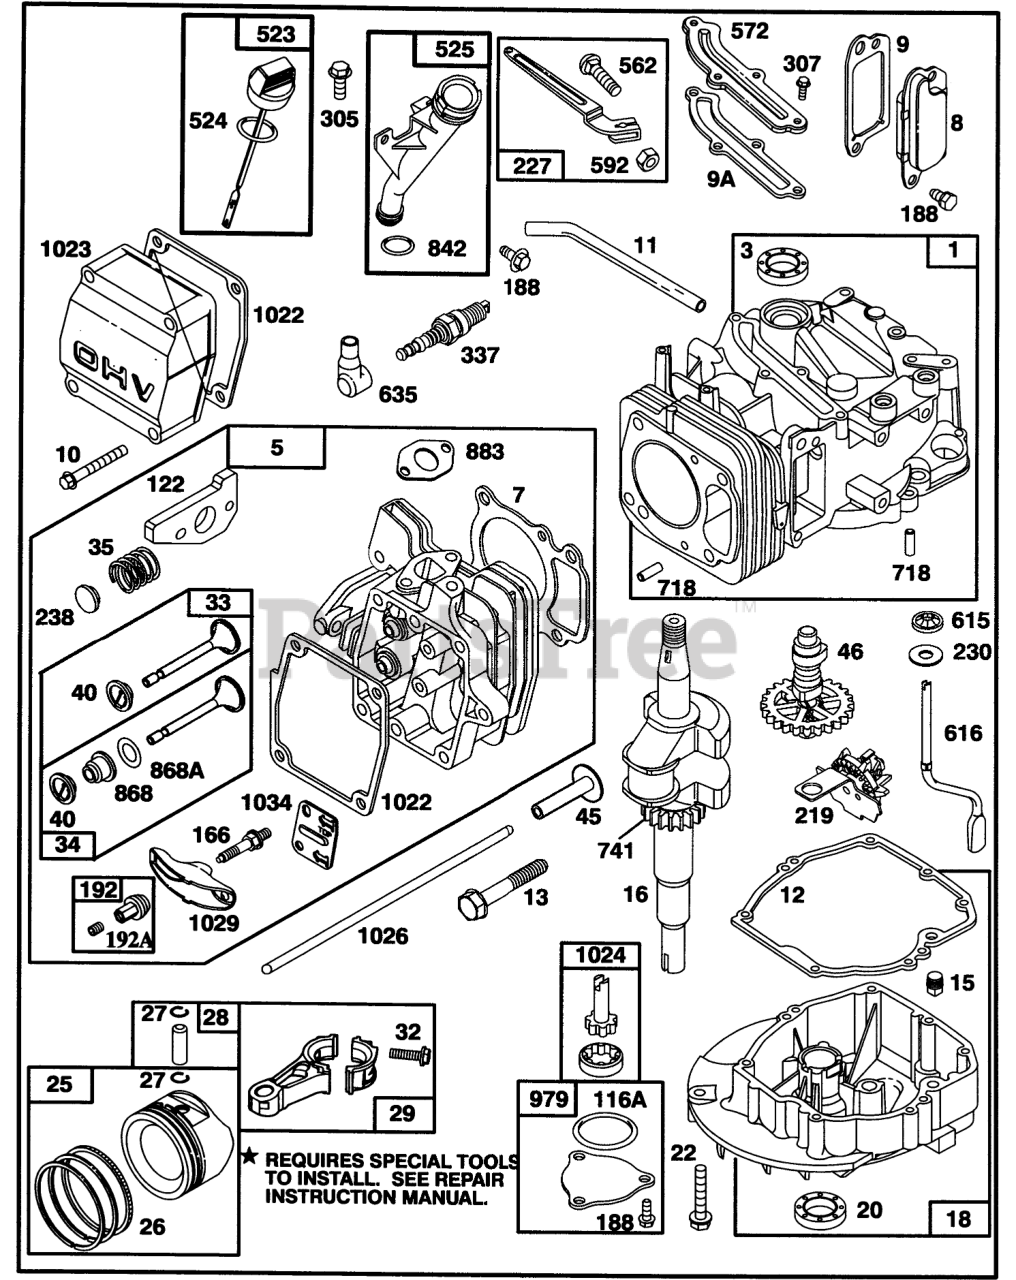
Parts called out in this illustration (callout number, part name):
1	CYLINDER ASSEMBLY
3	SEAL - OIL
5	CYLINDER HEAD
7	CYLINDER HEAD GASKET
8	Breather Assy
9	Gasket-Breather
9A	GASKET-BREATHER
10	HEX HEAD SCREW
11	BREATHER TUBE
12	ENGINE BASE GASKET
13	CYLINDER HEAD SCREW
15	PLUG - OIL DRAIN
16	CRANKSHAFT
18	ENGINE SUMP
20	SEAL-OIL
22	SCREW - ENGINE BASE
25	STD PISTON ASSEMBLY
26	STD RING SET
27	PISTON PIN LOCK
28	Pin Assy-Piston
29	CONNECTING ROD
32	Connecting Rod
33	EXHAUST VALVE
34	INTAKE VALVE
35	VALVE SPRING
40	SPRING RETAINER
45	VALVE TAPPET
46	CAM GEAR
116A	O RING SEAL
122	ADAPTER ASSEMBLY
166	Stud-Rocker Arm
188	SCREW - SEM
192	NUT - HEX SPECIAL
192A	Screw-Set
219	GOVERNOR/OIL SLINGER
227	GOVERNOR LEVER ASSEMBLY
230	WASHER
238	VALVE CAP
305	SCREW - HEX HEAD
307	SCREW - SEM
337	PLUG-SPARK
523	DIPSTICK-OIL
524	O-RING
525	OIL FILLER TUBE
562	GOVERNOR LEVER BOLT
572	BAFFLE - CYCLINDER
592	HEX NUT
615	FASTENER
616	GOVERNOR CRANK
635	SPARK PLUG ELBOW
718	DOWEL - SLEEVE
741	TIMING GEAR
842	O-RING
868	SealAssy-Valve
868A	Seal-Valve
883	EXHAUST GASKET
979	OIL PUMP COVER
1022	ROCKER COVER GASKET
1023	Cover-Valve
1024	OIL PUMP
1026	PUSH ROD
1029	ROCKER ARM
1034	PUSH ROD GUIDE
